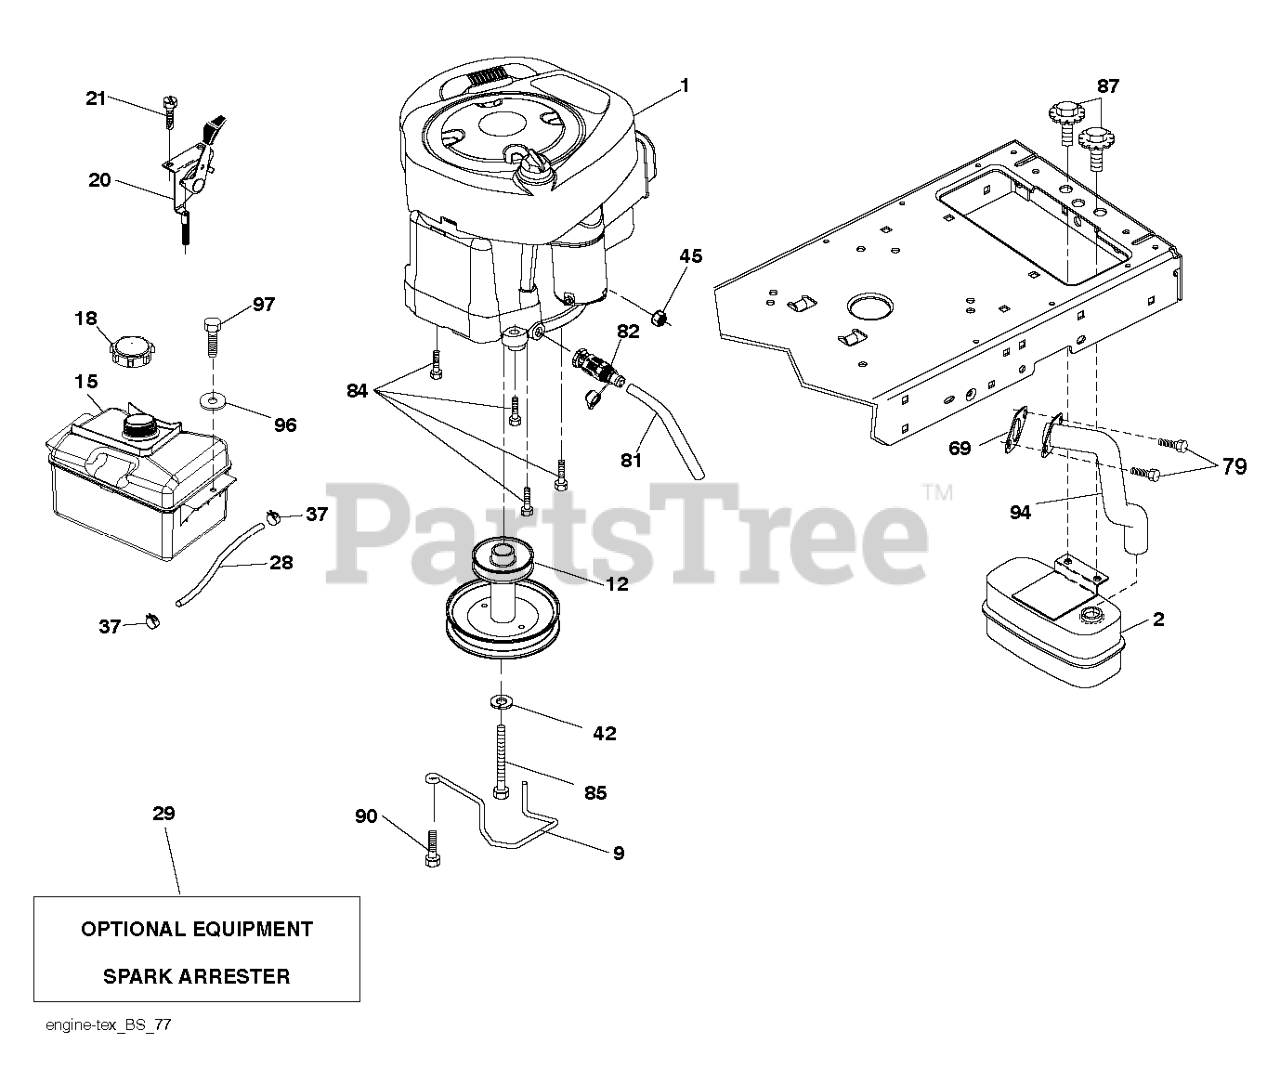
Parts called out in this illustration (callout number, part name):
2	MUFFLER.SINGLE.LRG.BRIGGS.KOHL
9	KEEPER BELT ENGINE
12	PULLY ENGINE
15	FUEL.TANK.ASM.NON-EPA
18	CAP ASM.FUEL.2.25"FR.
20	CONTROL.TH/CK.C.
21	SCREW.#10 X 0.750.BOS
28	LINE.FUEL.20
29	KIT.SPARK ARRESTOR 794945 B&S
37	HOSE CLAMP
42	LOCKWASHER
45	NUT
69	REPL BY 532 27 22-93
79	SCREW.SOCKET HD.5/16-1
81	TUBE, DRAIN OIL ASM.
82	VALUE.OIL.DRAIN
84	SCREW.3/8-16
85	BOLT HEX 7/16-20X4-1/4"
87	BOLT.5/16-18UNCX3/4 W/SEMS.BLK
90	SCREW 3/8-16X1
94	RP.EXHAUST.TUBE.B&S.28/31
96	WASHER
97	SCREW HEXWSHR 1/4-20X3/4
